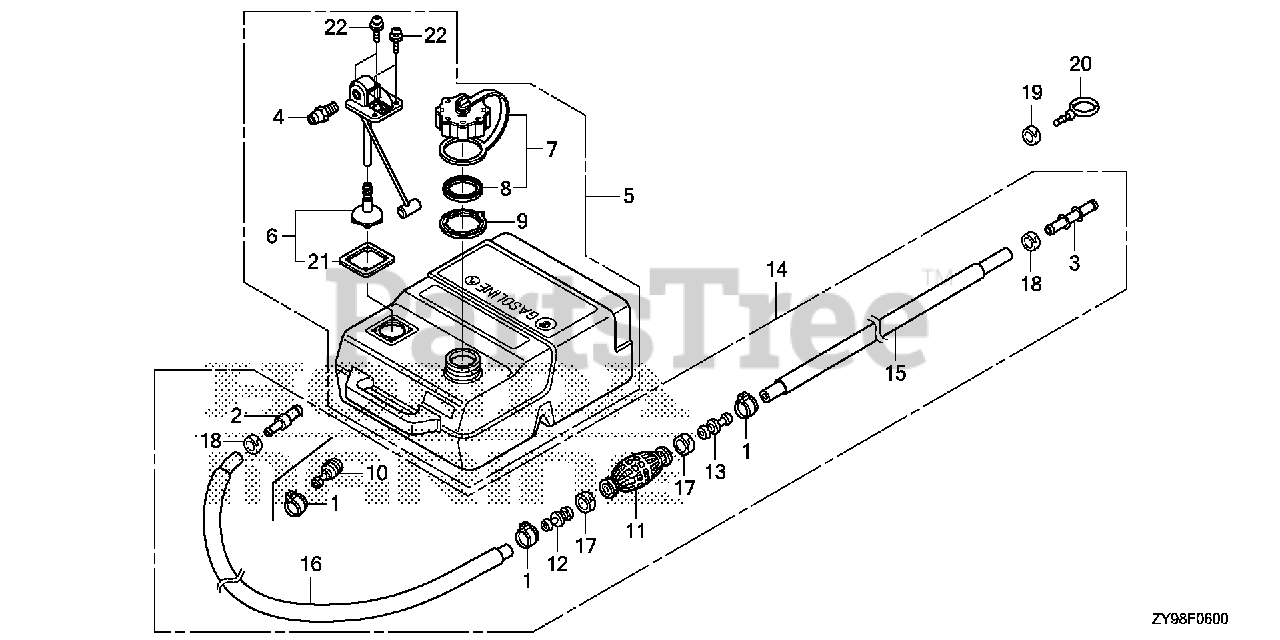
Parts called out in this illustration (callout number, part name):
1	CLAMP, FUEL TUBE (14.0)
2	JOINT, FUEL TUBE
3	JOINT, FUEL TUBE
4	FITTING, QUICK DISCONNECT
5	TANK ASSY., FUEL
6	FILTER KIT, FUEL
7	CAP, FUEL FILLER
8	GASKET, FUEL CAP
9	RETAINER, PRESSURE RELIEF
10	CONNECTOR, FUEL
11	BULB, PRIMER
12	VALVE, IN.
13	VALVE, OUTLET
14	TUBE ASSY., FUEL TANK
14	TUBE ASSY., FUEL TANK (CONNECTOR TYPE)
15	TUBE, FUEL SHORT
16	TUBE, FUEL LONG (7.3X2000)
16	TUBE, FUEL SHORT
17	BAND, TUBE CLIP (20MM)
18	BAND, TUBE CLIP (12.5MM)
19	BAND, TUBE CLIP (12.5MM)
20	PLUG, FUEL TUBE
21	GASKET, FUEL PICK-UP
22	BOLT-WASHER (5MM) (SEAL)
